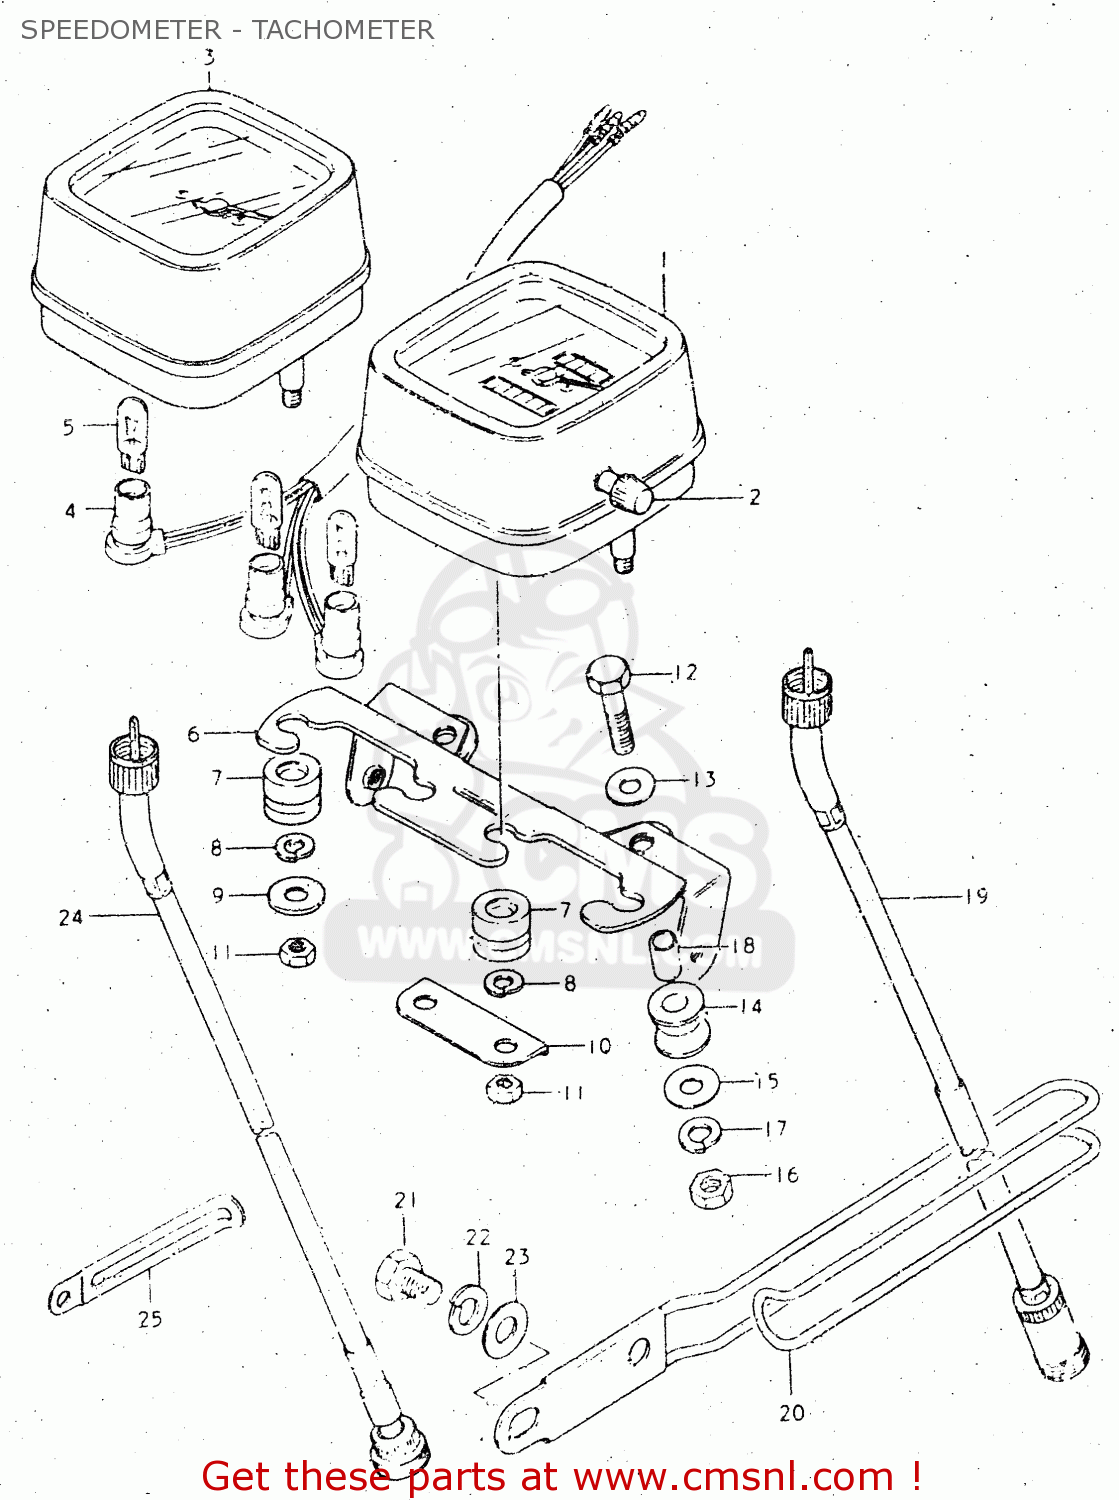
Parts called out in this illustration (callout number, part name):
1	SPEEDOMETER
2	KNOB,TRIP METER
3	TACHOMETER
4	SOCKET
5	BULB(6V,3W)
6	BRACKET
7	CUSHION
8	LOCK WASHER
9	WASHER,METER
10	PLATE,METER CONNECTING
11	NUT
12	BOLT
13	WASHER
14	CUSHION
15	WASHER
16	NUT
17	LOCK WASHER
18	SPACER (6.1X8X15.5)
19	CABLE ASSEMBLY,SPEEDOMETER
20	GUIDE,CABLE
21	BOLT 8X12
22	LOCK WASHER
23	WASHER
24	CABLE ASSY,TAC
25	CLAMP L:35
